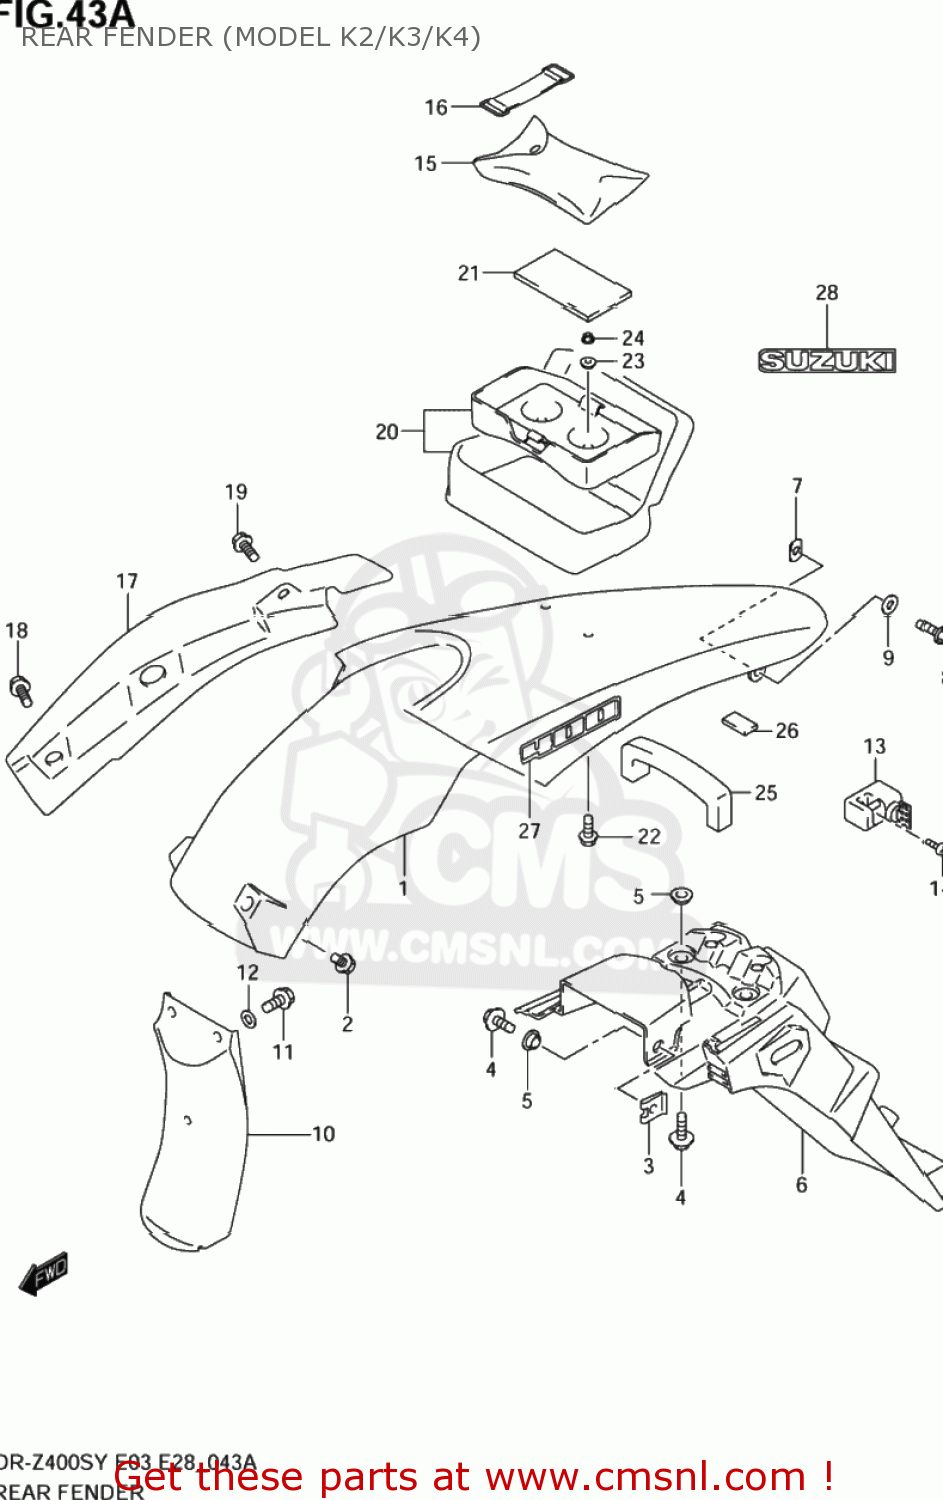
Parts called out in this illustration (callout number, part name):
1	FENDER,REAR
2	BOLT(6X16)
3	PLATE,REAR FENDER FITTING
4	BOLT(6X20)
5	WASHER
6	EXTENSION,RR FENDER
7	NUT,COWL
8	BOLT
9	WASHER (5X14X1)
10	MUDGUARD,RR FENDER FR
11	BOLT
12	WASHER
13	LOCK SET,HELMET
14	SCREW(6X14)
15	TOOL ASSY
16	BAND
17	MUDGUARD,RR FENDER,R
18	BOLT(6X18)
19	BOLT
20	BAG ASSY,SEAT TAIL
21	CUSHION,RR BAG
22	BOLT
23	WASHER
24	NUT
25	SEALER,SIDE COVER L
26	PROTECTOR(170X95X3.0)
27	EMBLEM,RR FENDER
28	EMBLEM,RR
